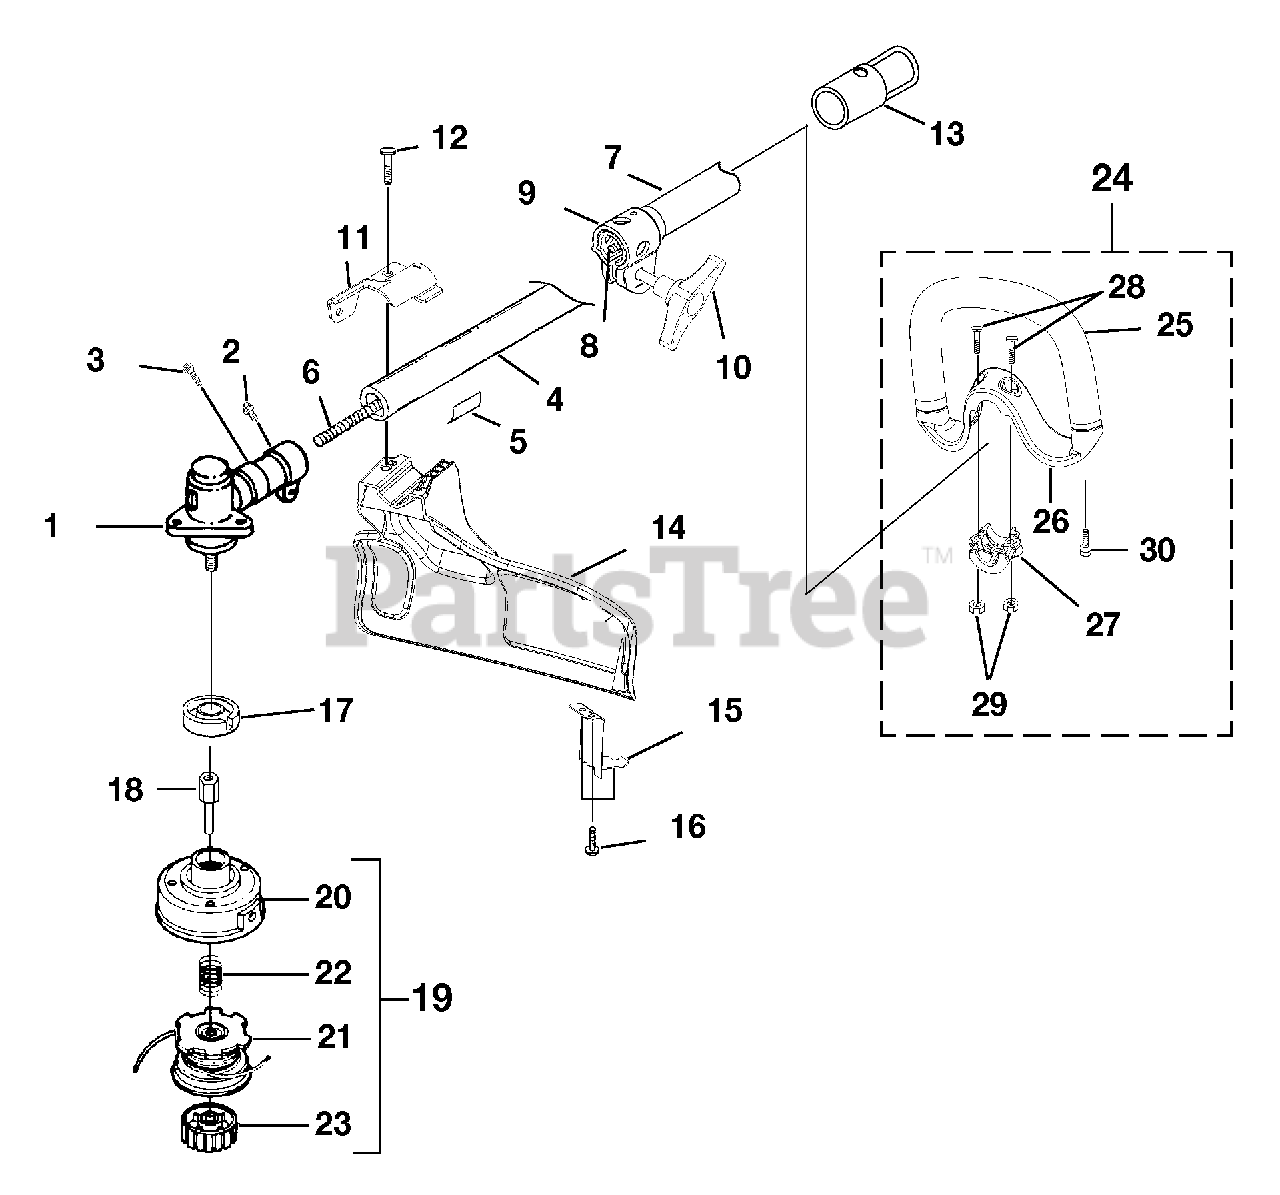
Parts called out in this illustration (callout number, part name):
1	GEAR HEAD
2	Screw, Cap Hd. (1/4-20 X 1.25")
3	Screw-Hex Hd. (10-24 x .625")
4	DRIVESHAFT HOUSING (Lower)
5	DECAL-Warning
6	SHAFT-Flexible
7	DRIVESHAFT HOUSING (Upper)
8	FLEXSHAFT-w/Collar & Liner
9	COUPLER KIT
11	CLAMP-Grass Shield
12	SCREW-Hex Hd. (1/4-20 x 1.25")
13	END CAP
14	GRASS SHIELD
15	BLADE-Cut-off
16	SCREW-Pan Hd. (8-16 x 1/2")
17	WASHER-Flanged
18	ADAPTER-Stringhead
19	STRINGHEAD-Complete (.080")
20	HOUSING & EYELET (Dual Line)
21	SPOOL & STRING (.080")
22	SPRING-Compression
23	RETAINER-Spool (LH Thread)
24	HANDLE-Complete
25	HANDLE W/Grip
26	CLAMP - "M"
27	CLAMP-Assist Handle
